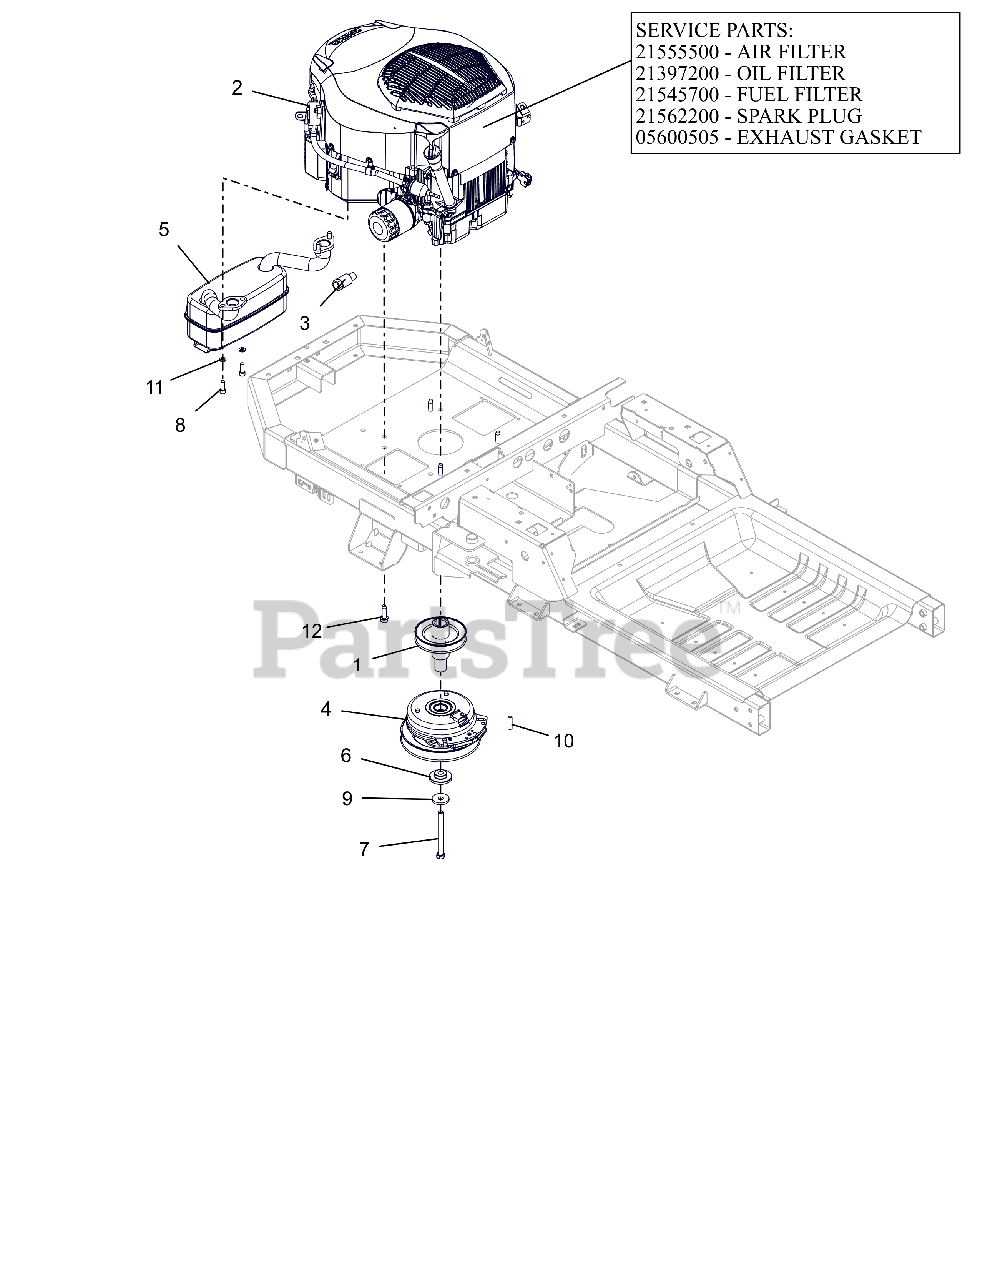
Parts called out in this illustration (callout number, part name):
1	WLDMT, DRIVE SHEAVE-X
2	ENGINE, KOHLER 24HP TWIN
3	DRAIN, OIL
4	CLUTCH,105FTLB MONOPOLE 6.83"
5	MUFFLER - KOHLER
6	BSHG-FLG .469X1.06X.574X2.0
7	BLT-HEX.438-20X4.5GR8YZ NYTORQ
8	SCR-CAP .31-18X.88 S/HD G8 ZCC
9	WASHER, 7/16" SPRING DISK
10	KEY-SQ .25 X 1.25 X .25 SAE
11	WSHR,LK-REG .312X.078 ZCC
12	SCR,TAP .375-16X1.25HWH TR ZCC
